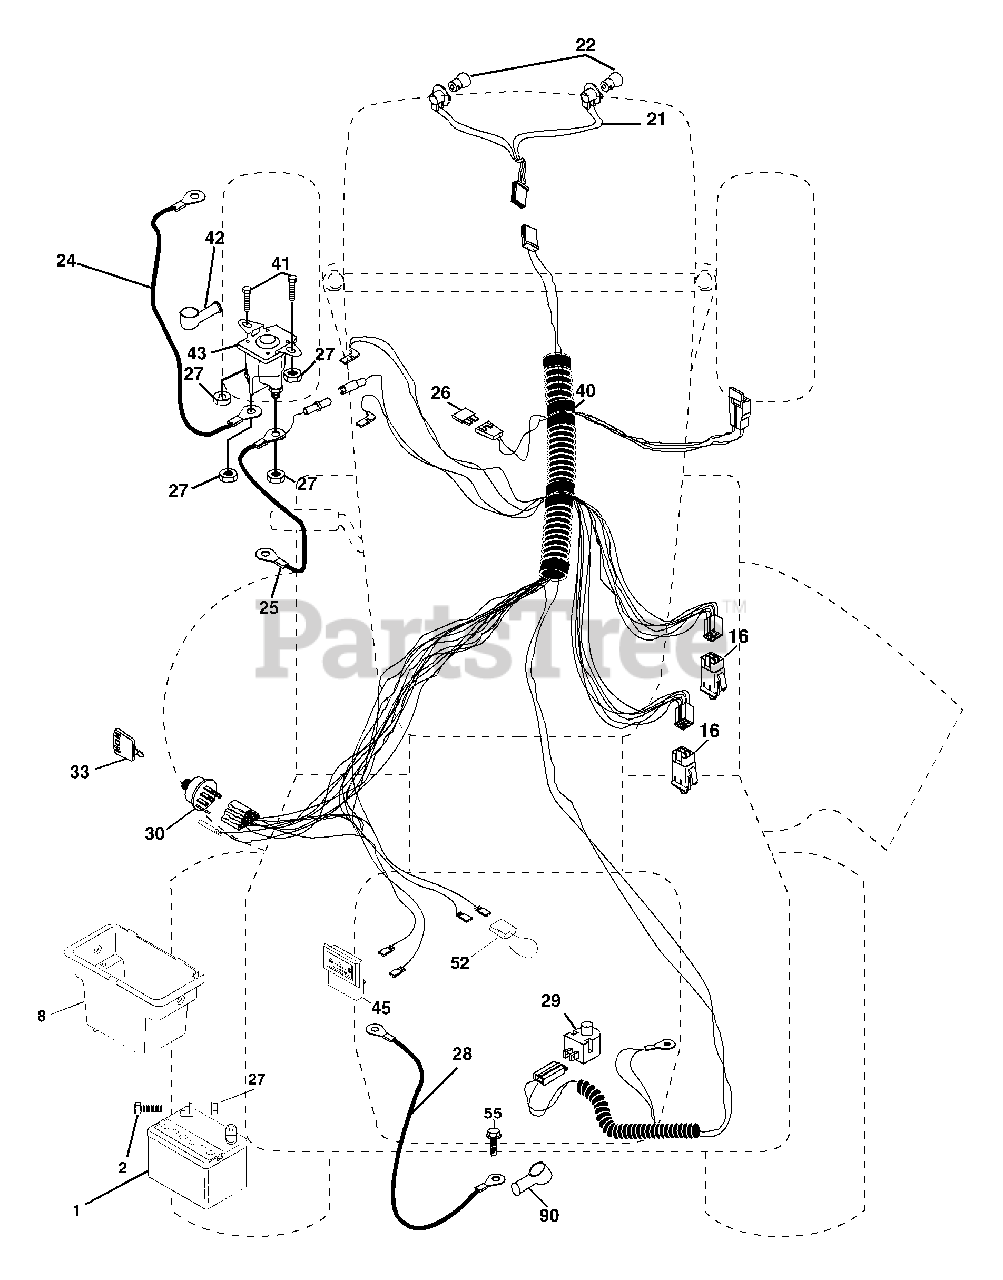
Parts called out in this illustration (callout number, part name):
1	Battery
2	Bolt Hex Hd 1/4-20 unc x 3/4
8	Box Battery
16	Switch Interlock
21	Harness Socket Light
22	Bulb, Light # 1156
24	Cable Battery
25	Cable Battery 6 Ga. Red w/16 wire 44"
26	Fuse
27	Nut Keps Hex 1/4-20 unc
28	Cable Ground 12" Blk 6 Ga.
29	Switch Plunger Nc Gray
30	Switch Ign
33	Key Ign Molded Generic
40	Harness Ign
41	Bolt Fin Hex 1/4-20 unc x 1/2
42	Cover Terminal Red
43	Solenoid
45	Ammeter Rectangular
52	Protection Loop
90	Cover Terminal
